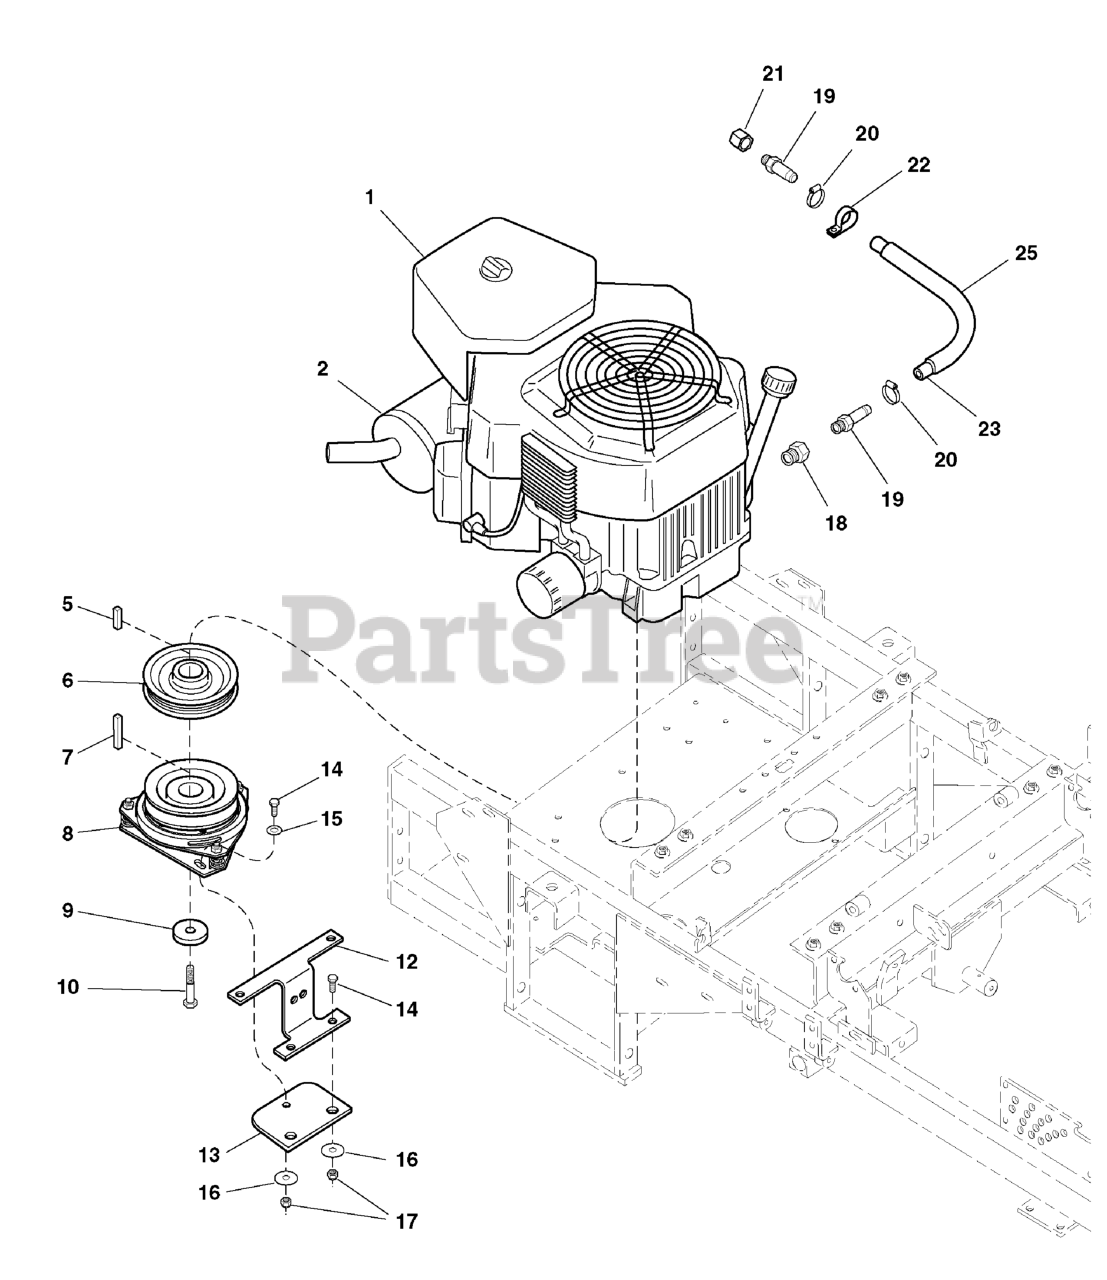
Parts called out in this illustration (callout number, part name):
2	MUFFLER, Kohler
5	KEY, 1/4 SQ. X 1
6	PULLEY, Crankshaft
7	KEY, 1/4 SQ. X 2
8	ELECTRIC CLUTCH
9	SPACER, .45 x 1.88 x .38
10	CRANKSHAFT BOLT, 7/16 x 2-1/4
11	CRANKSHAFT BOLT, 7/16 x 1-1/2
12	ANCHOR, Clutch
13	CLUTCH ANCHOR PAD
14	BOLT, 5/16-18 X 3/4 GD5
15	WASHER, 5/16" SAE
16	WASHER, 3/8" Fender
17	NUT, 5/16-18 Hex Nylon Lock
18	ADAPTER, Oil Drain
19	FITTING, 3/8NPT-1/2" Hose, Straight
20	CLAMP, #6 Hose
21	CAP, 3/8 NPT
22	CLAMP, Vinyl
23	HOSE, 16" Long
24	HOSE, 14"
25	WIRE LOOM, 14"
26	WIRE LOOM, 12"
